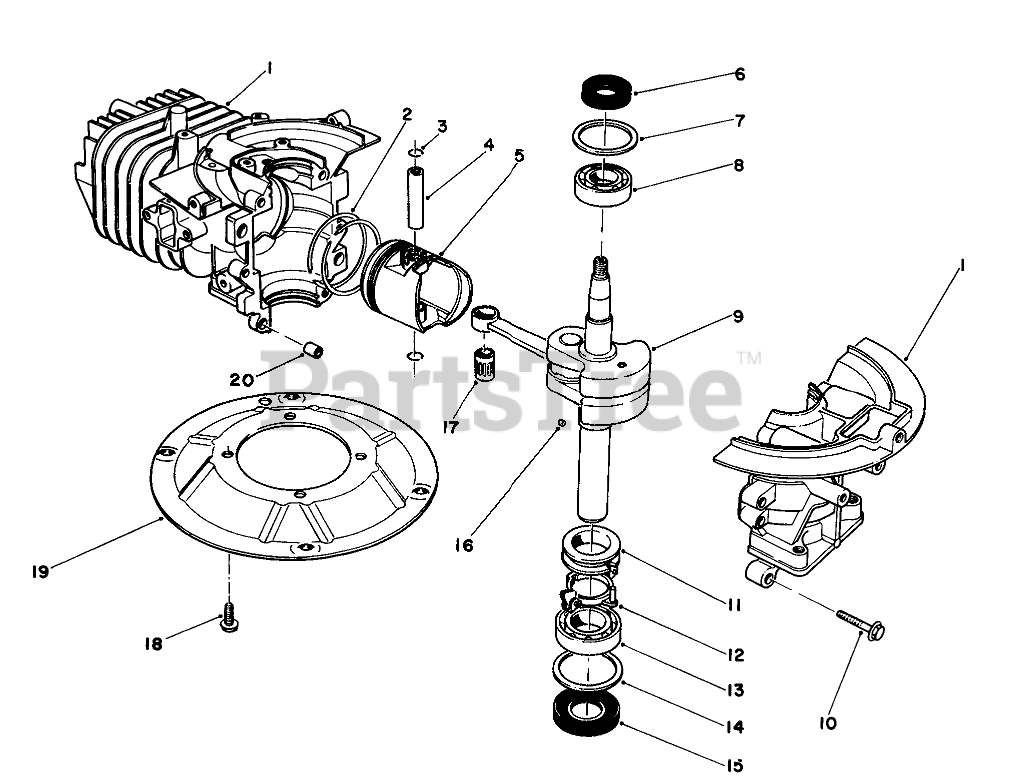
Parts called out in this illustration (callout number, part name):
1	Crankcase-Cylinder Assy.
1	CRANKCASE
2	RING SET
4	PIN-PISTON
5	Piston
6	OIL SEAL
7	WASHER-UPPER
8	BEARING-UPPER
9	CRANKSHAFT ASM
11	SPACER
12	BRACKET
13	LOWER BRG
14	WASHER-LOWER
15	SEAL-OIL
17	BEARING
19	PLATE-MOUNTING
